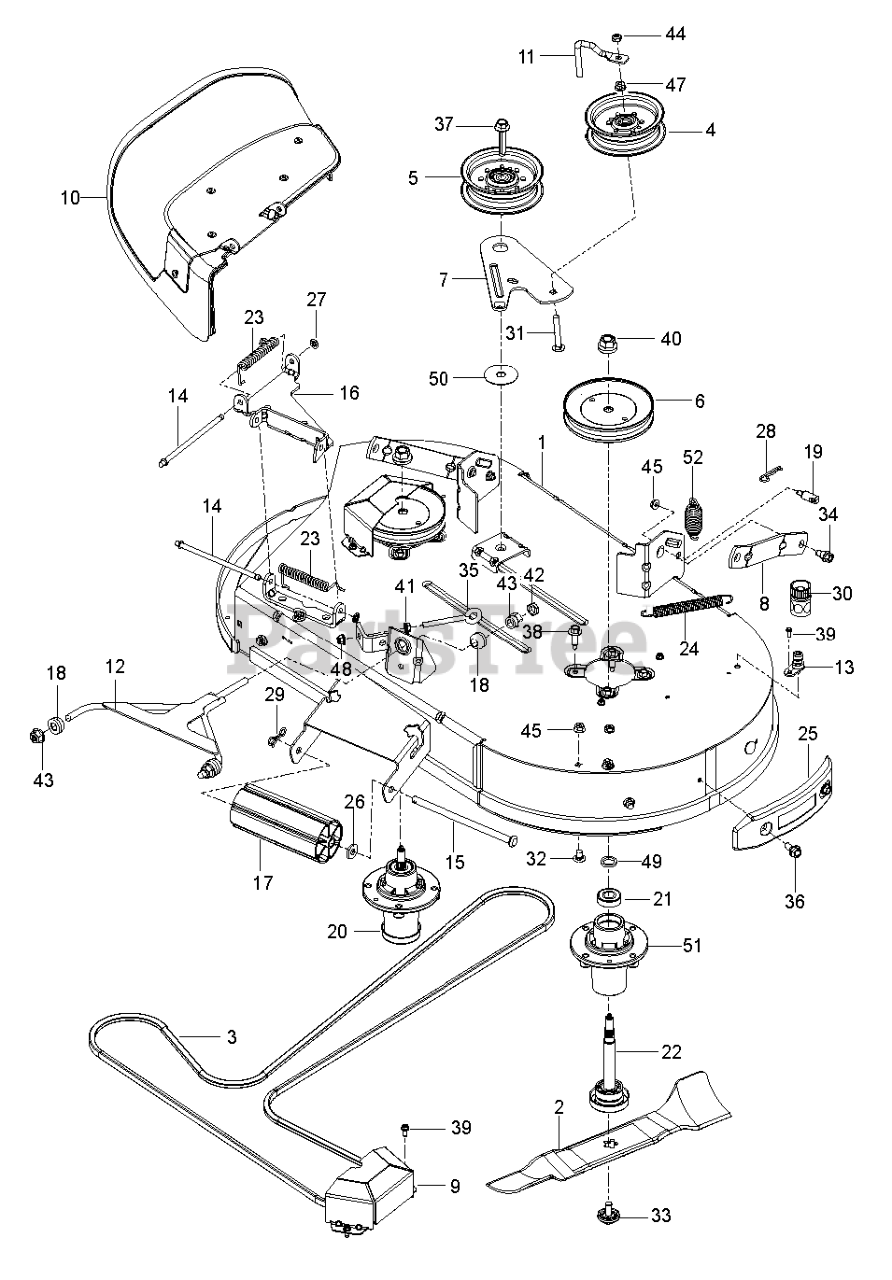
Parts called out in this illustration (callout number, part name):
1	DECK KIT.42".ORANGE.SERVICE
2	BLADE.42.FCS.BAGGING.BLADE.RAW
3	BELT.42.FCS.ZTR.DECK.DRIVE
4	PULLEY.IDLER.2006
5	PULLEY.IDLER.MWR.STATI.LH
6	PULLEY MANDREL 5.0"
7	ARM.42"FCS.CLUTCHING.X431
8	ARM.RFIXED.MOWER.SUSPNSIONX431
9	COVER.42".MANDREL.FCS.PNT.498
10	DEFLECTOR.ASM.42.FCS.ORANGE
11	KEEPER.BELT.IDLER.54"T
12	LINK.RZ.FRONT.WELDMENT.E-DIP
13	PORT.WASHOUT
14	ROD.HINGE
15	ROD.ROLLER.NOSE.NARROW.48"
16	BRACKET.42".FCS.DBLE.HINGEX668
17	NOSE ROLLER 48"
18	BUSHING SPHERICAL SUSP. FRONT
19	STUD.FASTNER.W/ANTI-ROTATE
20	MANDREL ASM, CAST IRON
22	SHAFT ASM MANDREL
23	SPRING.42.FCS.DEFLECTOR
24	SPRING.MOWER.DRIVE.ELECTRIC
25	BUMPER.42.CLEARCUT.TRIMSDE.ASM
25	BUMPER.42CC.TRIM.SIDE.ASSY.HUS
26	BUSHING.NOSE.ROLLER
27	NUT PUSH M
28	HAIRPIN #4
28	PIN.COTTER.7/16.BOW TI.
29	PIN.COTTER.5/16.BOW TI
30	COUPLING.QUICK CONNECT
31	CARRIAGE BOLT 3/8-16 X
32	CARRIAGE BOLT 5/16C X 5/8"
33	BOLT.WASHER.ASM.7/16-2
34	BOLT.SHOULDER
35	EYE BOLT 5/16 X 3.50
36	SHOULDER BOLT 5/16-18TT
37	SCREW.7/16-14 X 2.125.WASHER
38	BOLT.HEX.WASHR.HED.313-18X1.19
39	SCREW.1/4-20X5/8
40	NUT.FLANGE.LOCK.TOP
41	NUT 5/16C WHIZ
42	NUT **
43	NUT, LIFT LINK 7/16-20
44	NUT LOCK FLG 3/8-16 UNC
45	NUT LOCK HEX FLANGE 5/16-18
48	5/16-18 NYLOC FLANGE NUT
49	WASHER.SPACER.MANDREL
51	MANDREL, HOUSING - CAST IRON
